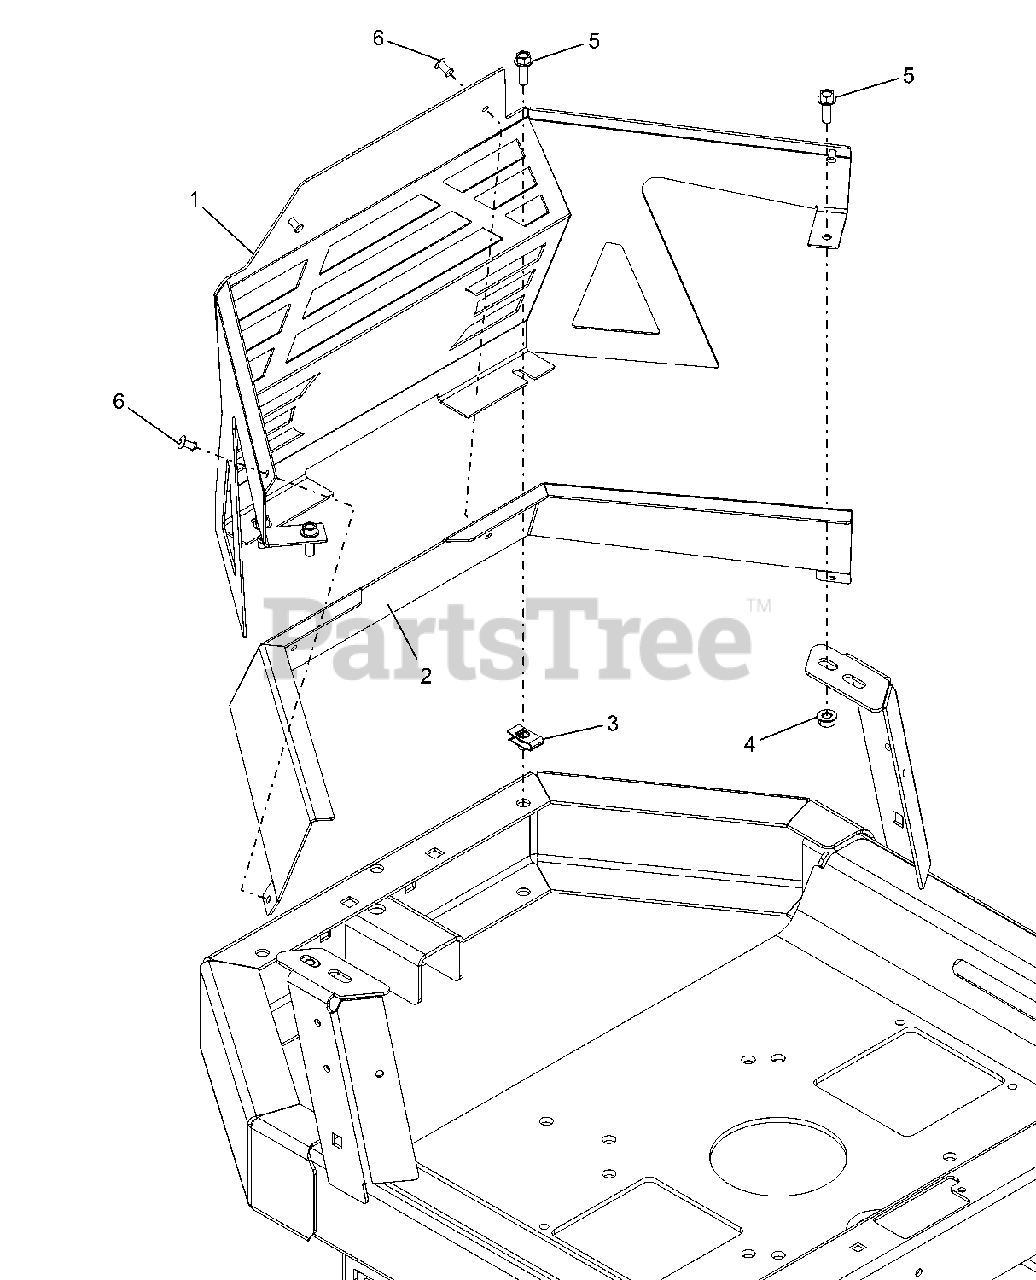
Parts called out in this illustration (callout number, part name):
1	SHROUD, REAR ENGINE-ARIENS XL
2	WLDMT, ENGINE SHROUD TRIM-XL
3	NUT-RTNR .25-20X.56
4	@NUT-LK-TOP-FLG .25-20 YWZC
5	BLT-HEX .25-20X.75 HWH YZ GR5
6	RIVET, #66 STEEL POP PD BLACK
